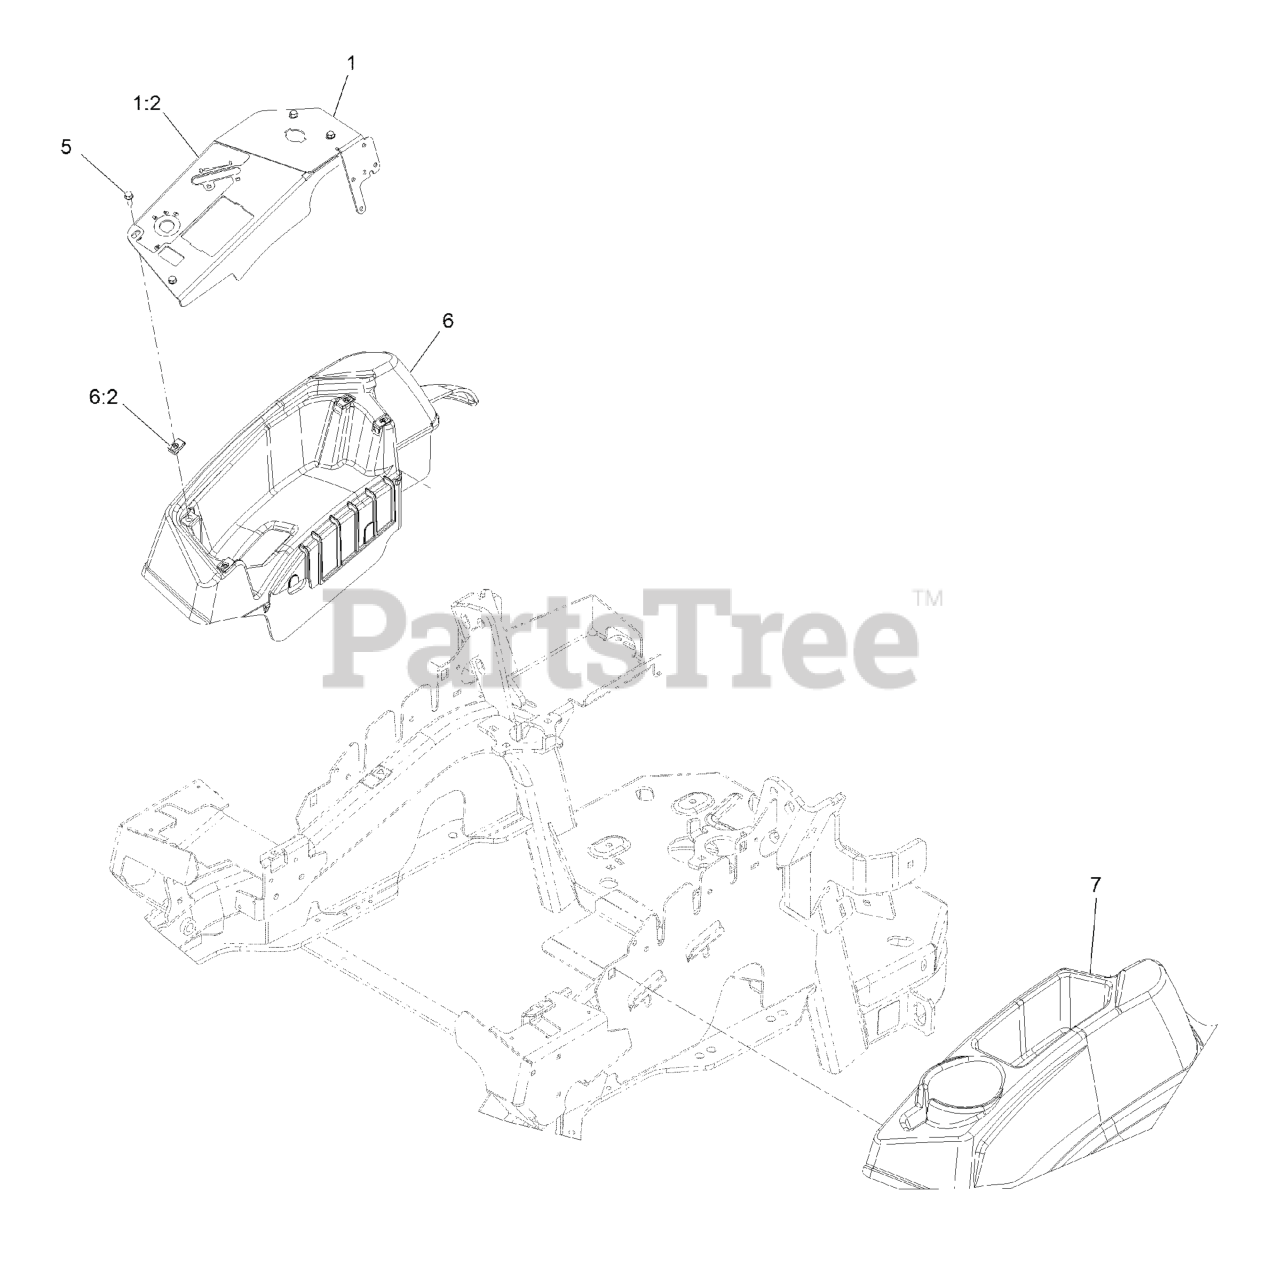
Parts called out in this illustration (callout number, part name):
1	PANEL-CONTROL W/DECAL SHM-EFI
1:2	DECAL-CONTROL PANEL-EFI
5	SCREW-HWH
6	CONSOLE,RH AS ASM
7	CONSOLE, LH AS
